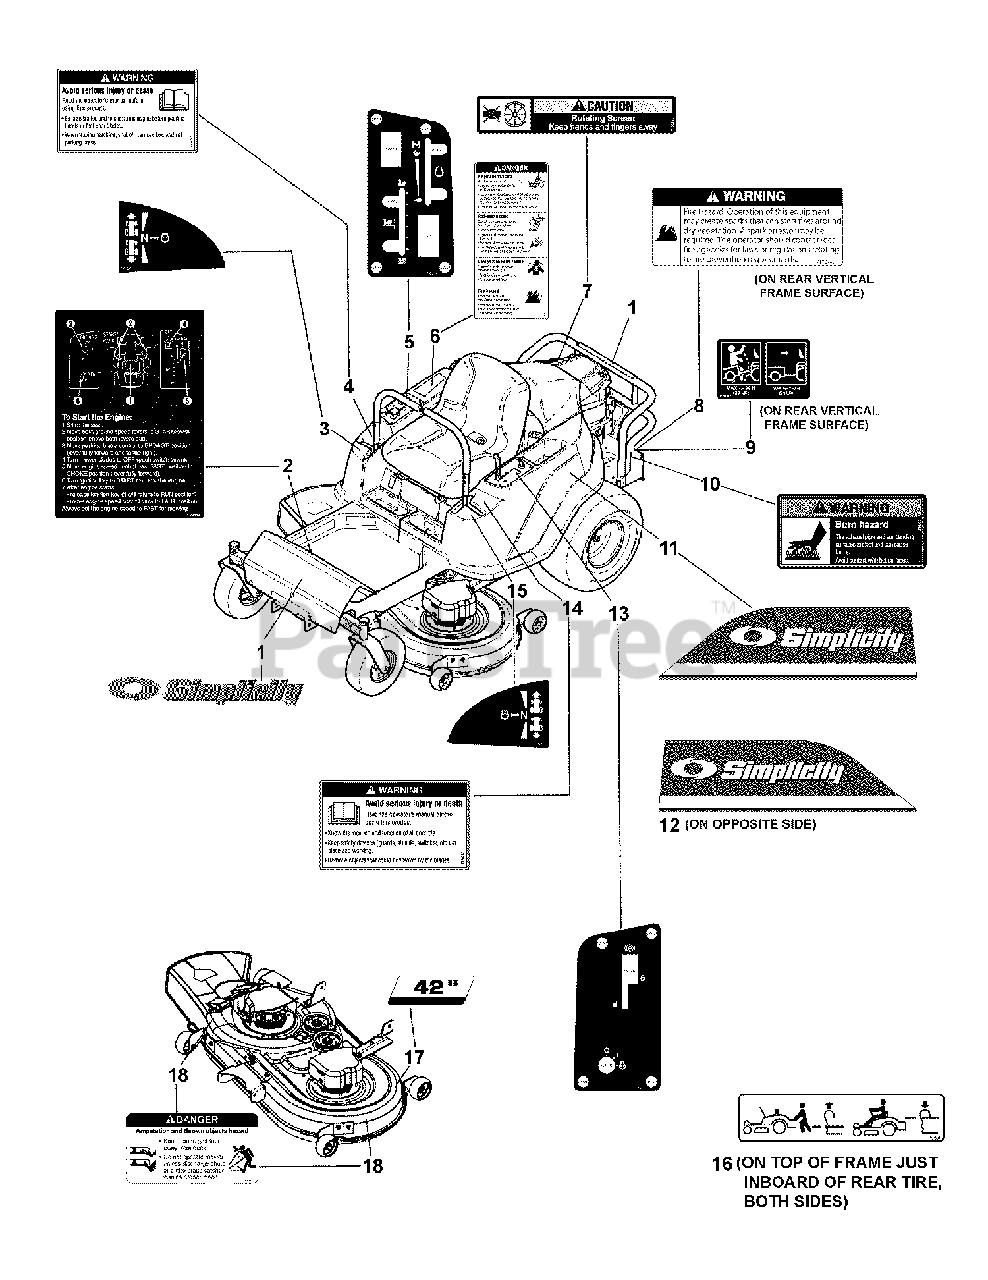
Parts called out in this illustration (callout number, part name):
1	DECAL, Simplicity Silver & Blue w/Icon
2	DECAL, Instructional
3	DECAL, Handle, Ground Speed, RH
4	DECAL, Warning, English, RH
5	DECAL, Control Panel, RH
6	DECAL, Danger, Hazards, English
7	DECAL, Caution, Rotating Screen
8	DECAL, Spark Arrestor
9	DECAL, Weight Limitation
10	DECAL, Warning, Burn Hazard
11	DECAL, LH Fender, Smi ZT2000
12	DECAL, RH Fender, Smi ZT20000
13	DECAL, Control Panel, LH
14	DECAL, Warning, English, LH
15	DECAL, Handle, Ground Speed, LH
16	DECAL, Release, Transaxle
17	DECAL, 42" Deck, 2006 Silver/Black
18	DECAL, Danger Do Not Operate w/o Deflector
